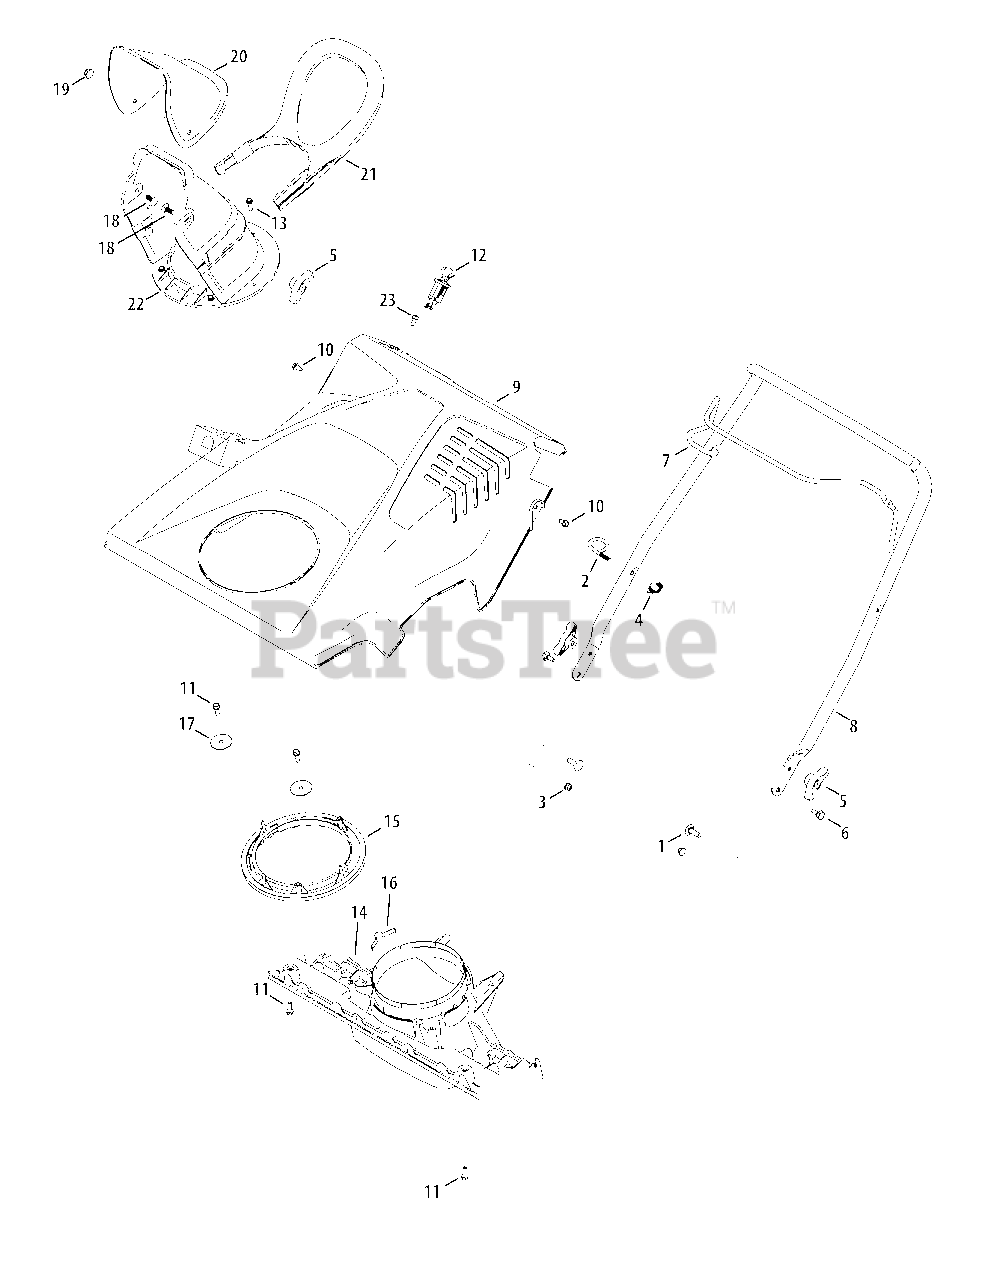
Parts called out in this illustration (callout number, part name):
1	Carriage Bolt, 5/16-18 x 1.00
2	Eye Bolt, 1/4-20
3	Flange Lock Nut, 1/4-20
4	Knob Handle
5	Wing Knob
6	Shoulder Screw, .375 x .148 x 1/4-20
7	Auger Bail
8	Upper Handle
9	Top Cover (Black w/o electric start)
10	Hex Screw, 1/4-14 x .500
11	Screw, Hi-Lo:1/4-15, 0.75
12	Ignition Switch Assembly
13	Hex Washer Screw, 1/4 x .750
14	Chute Adapter
15	Chute Ring
16	Chute Adjustment Spring
17	Flat Washer, .28 x 1.5 x .066
18	Carriage Bolt, 5/16-18 x .750
19	Flange Lock Nut, 5/16-18
20	Upper Chute
21	Chute Handle
22	Lower Chute
23	Hex Washer Screw, 1/4-15 x .50
